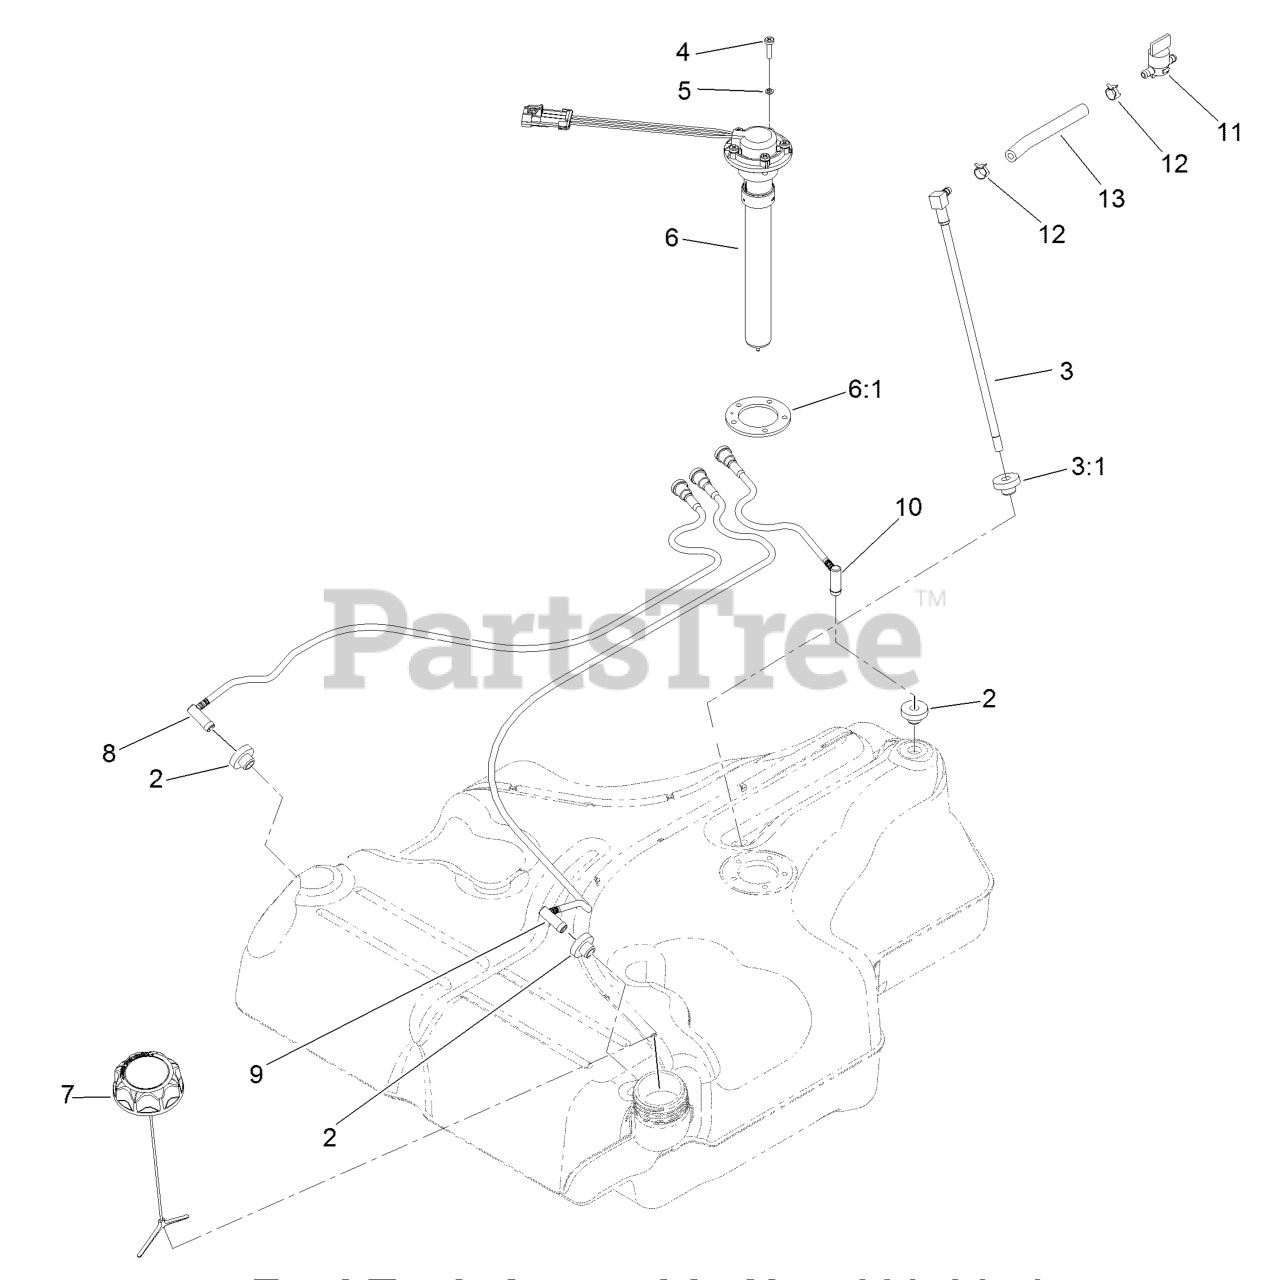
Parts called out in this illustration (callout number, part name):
2	BUSHING
3	FUEL LINE KIT (WITH GROMMET)
3:1	BUSHING
4	SCREW-PAN
5	WASHER-LOCK
6:1	GASKET-SENDER, FUEL
8	RH VENT LINE KIT (WITH GROMMET)
9	LH VENT LINE KIT (WITH GROMMET)
10	REAR VENT LINE KIT (WITH GROMMET)
11	VALVE-FUEL
12	CLAMP-HOSE
13	HOSE-FUEL
